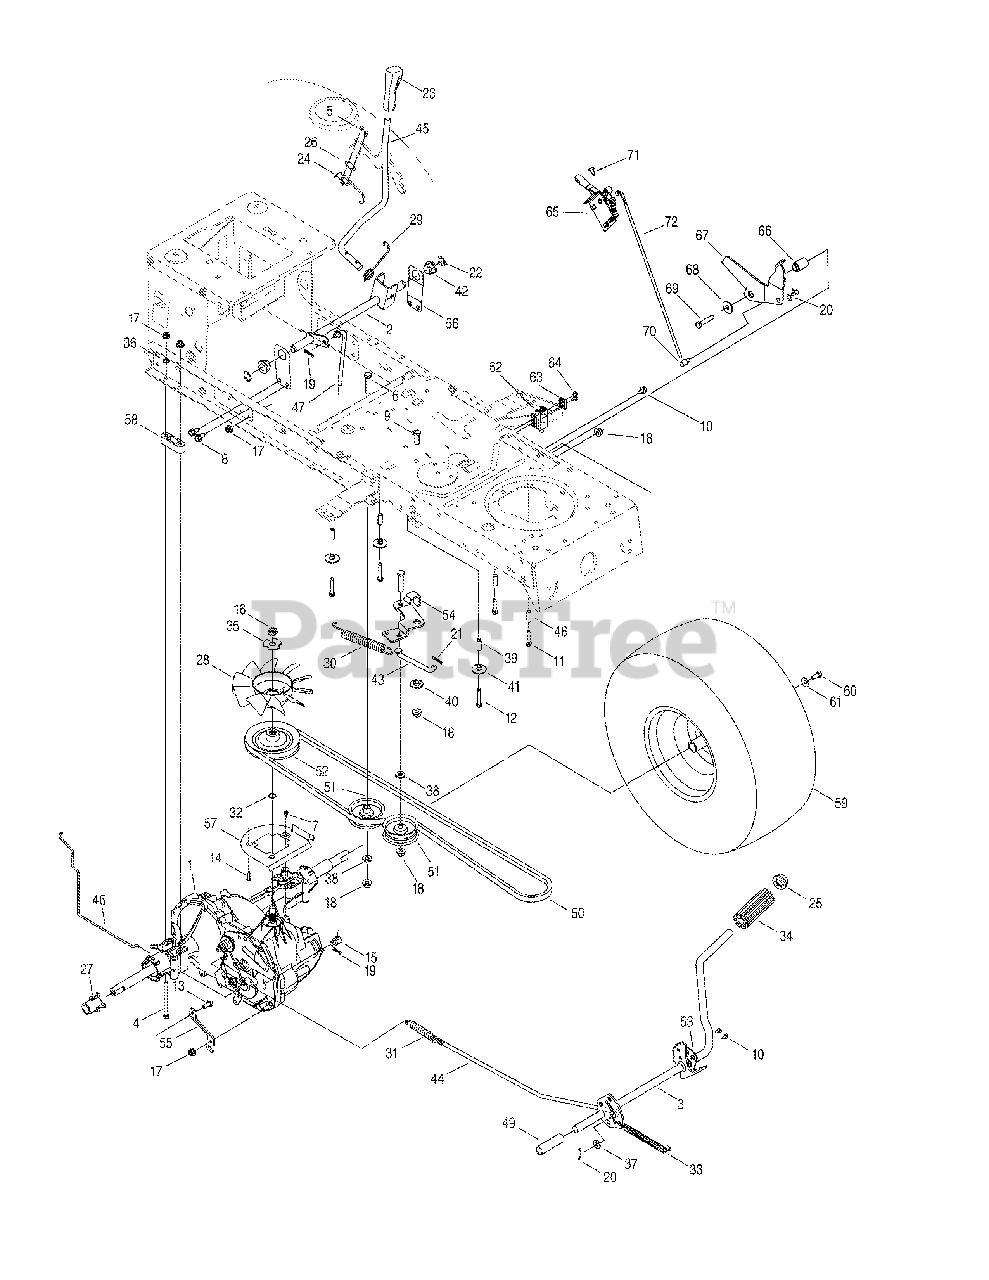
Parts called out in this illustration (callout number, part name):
1	Transmission Ass’y
2	Hydro Hand Control Ass’y
3	Hydro Pedal Assembly
4	Hex Scr 5/16-18 x 2.75
4	Hex Scr 5/16-18 x 3.5
5	Hex Wash HD AB S-Tapp Scr #8-.50
6	Hex Scr 3/8-16 x 1.75
7	Screw #10-16 x .50
8	S-Tapp Scr 5/16-18 x .75
9	Hex Scr 3/8-16 x 1.0
10	Hex Scr 5/16-18 x 0.625
11	Hex Bolt 1/4-20 x 1.25
12	Screw 1/4-20 x 1.25
12	Screw 1/4-20 x 1.75
13	Hex Bolt 5/16-18 x .75" Lg. Gr. 5
14	Screw, #10-24 x .75
15	Ferrule
16	Jam L-Nut 1/2-20
17	Flange Locknut 5/16-18 Gr. F, Nylon
18	Flange Locknut 3/8-16 Gr. F, Nylon
19	Int. Cotter Pin .072 x 1.13" Lg.
20	Bow Tie Cotter Pin
21	Cotter Pin 3/32 dia x 1.25 Lg.
22	E Ring .625 Dia.
23	Handle Grip
24	Hydro Spring Switch
25	Push Cap 5/8" Dia Rod
26	Insulator Nut Plate
27	Sleeve, .765 x 1.5" Lg.
28	Hydro Fan
29	Torsion Spring
30	Ext. Spring .75 Dia. x 6.02
31	Ext. Spring .59 OD x 4.00 Lg.
32	Wire Ring
33	Extension Spring .50 dia. x 6.37
34	Foot Pad
35	Lockwasher Trans Hydro
36	Lockwasher 5/16 ID
37	Flat Washer .344 x .750 x .120
38	Flat Washer .407 x .812 x .135 HT
39	Spacer .260 x .375 x 1.030 Lg.
39	Spacer .260 x .372 x 1.420
40	Screw, 3/8-16 x 1.75
41	Shoulder Spacer .375 OD x .284
41	Flat Washer .285 x 1.25 x .06
42	Hex Flange Bear ing .630 ID
43	Declutching Rod
44	Brake Rod
45	Hydro Control Handle
46	Hydro Bypass Rod
47	Hydro Control Rod
48	Spacer, .260 x .375 x 1.030" Lg.
49	Spacer, .640 x .76 x 2.6" Lg.
50	V-Belt 4L SEC x 78.2 Lg
51	Flat Idler Pulley 2.75 OD
52	Input Pulley
53	Support Pedal Bracket
54	Idler Arm
55	Torque Bracket
56	Handle Bracket
57	Belt Disengage Support Bracket
58	Spacer, T-Axle, 46" only
59	Wheel Assembly Complete, 20 x 8 x 8
59	Tire Only, 20 x 8 x 8, Square Shoulder
60	Hex L-Screw 5/16-24 x 0.75 Gr. 5
61	Cupped Washer .345 ID x .88 OD x .060
62	Interlock Switch
63	Switch Plate
65	Hydro Ass'y
66	Flg,. Spacer
67	Latch Ass’y, Engagement (RMC)
68	Flat Washer .411 ID x 1.25 OD x .10
69	Hex Screw 3/8-16 x 2.0 Gr. 5
70	Adjustment ferrule
71	Screw, 1/4-20 x .5
72	Control Speed Selector Rod
